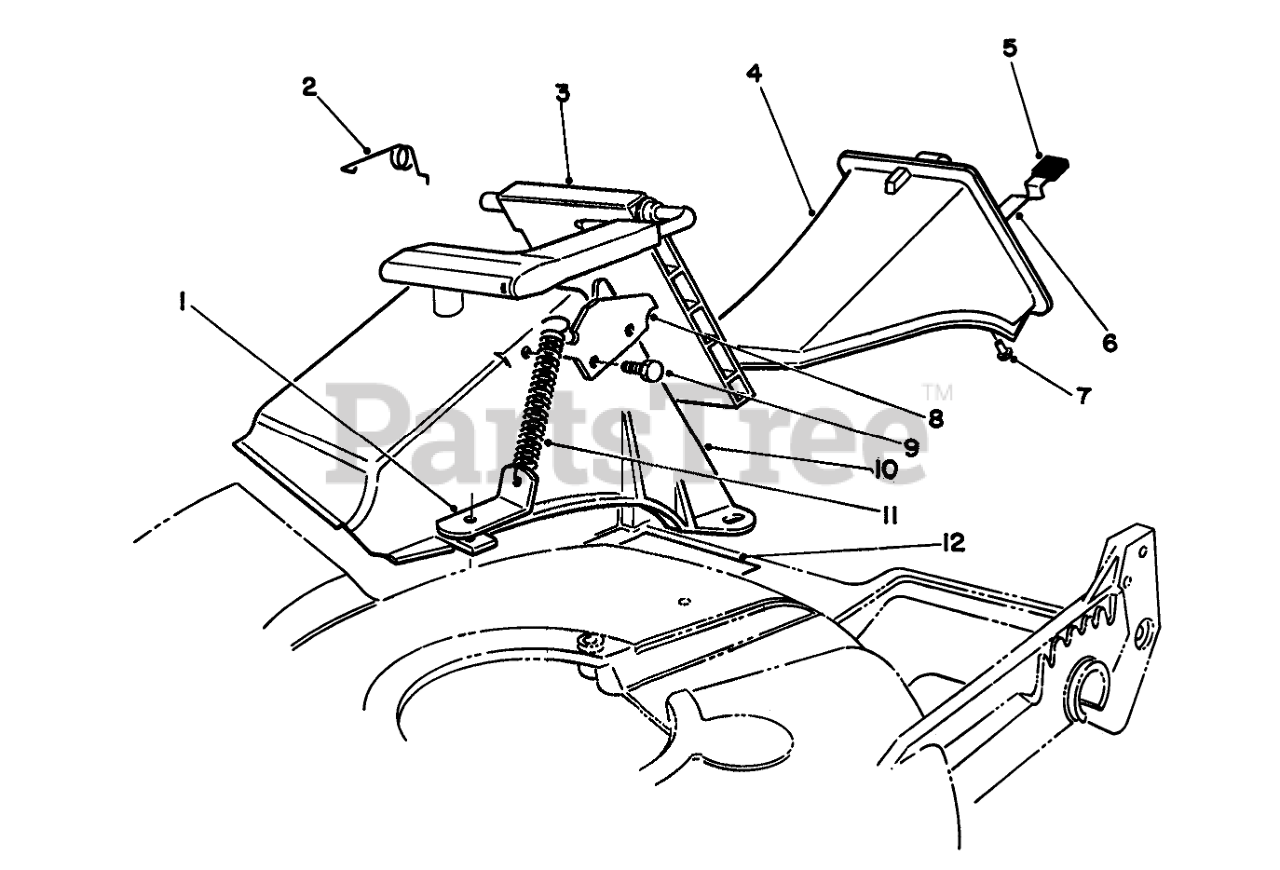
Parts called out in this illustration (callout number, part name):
1	BRACKET-SPRING
2	RETAINER-DOOR
3	DOOR ASSEMBLY
4	Plug-Assembly (Incl. Ref. #5-7)
5	GRIP-LATCH
6	LATCH-PLUG, DISCHARGE
7	RIVET-HEAD, FLAT
8	DOOR LATCH PLATE
9	SCREW-PLASTITE
10	DISCHARGE TUNNEL
11	SPRING-DOOR
12	DECAL - CAUTION
